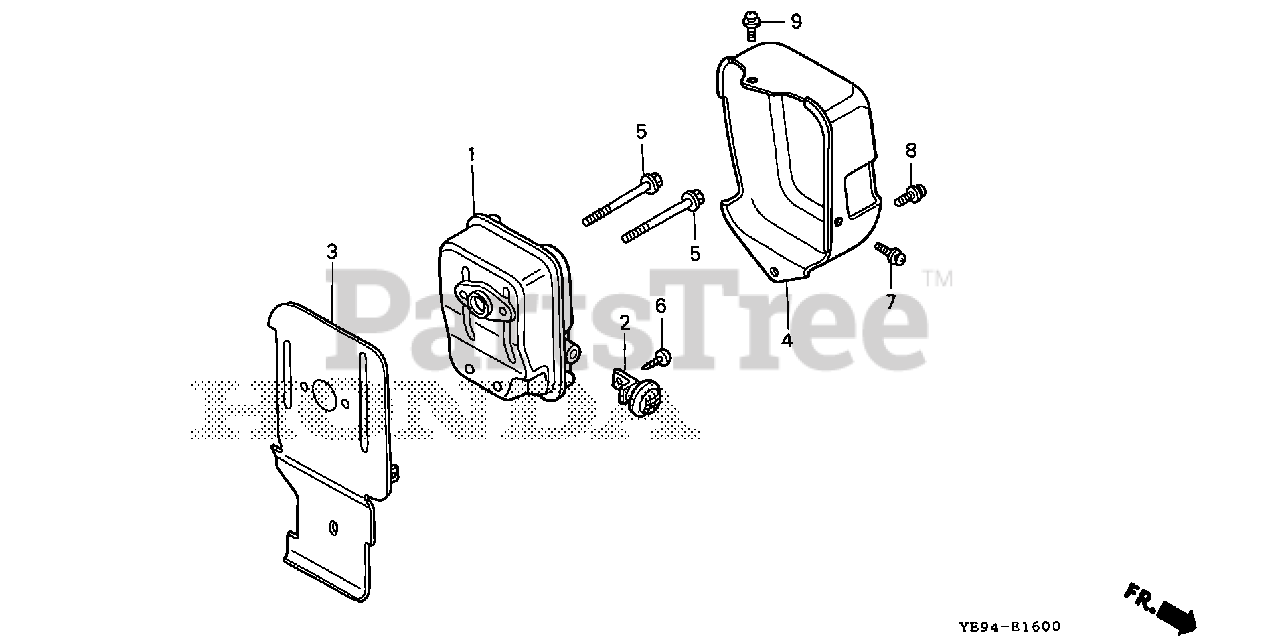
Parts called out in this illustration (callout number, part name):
1	MUFFLER
2	ARRESTER, SPARK
3	GUIDE, AIR EX.
4	INNER COVER, TOP
5	BOLT, FLANGE (5X50)
6	SCREW, TAPPING (4X6)
7	SCREW-WASHER (5X8)
8	SCREW-WASHER (5X10)
9	SCREW-WASHER (5X16)
